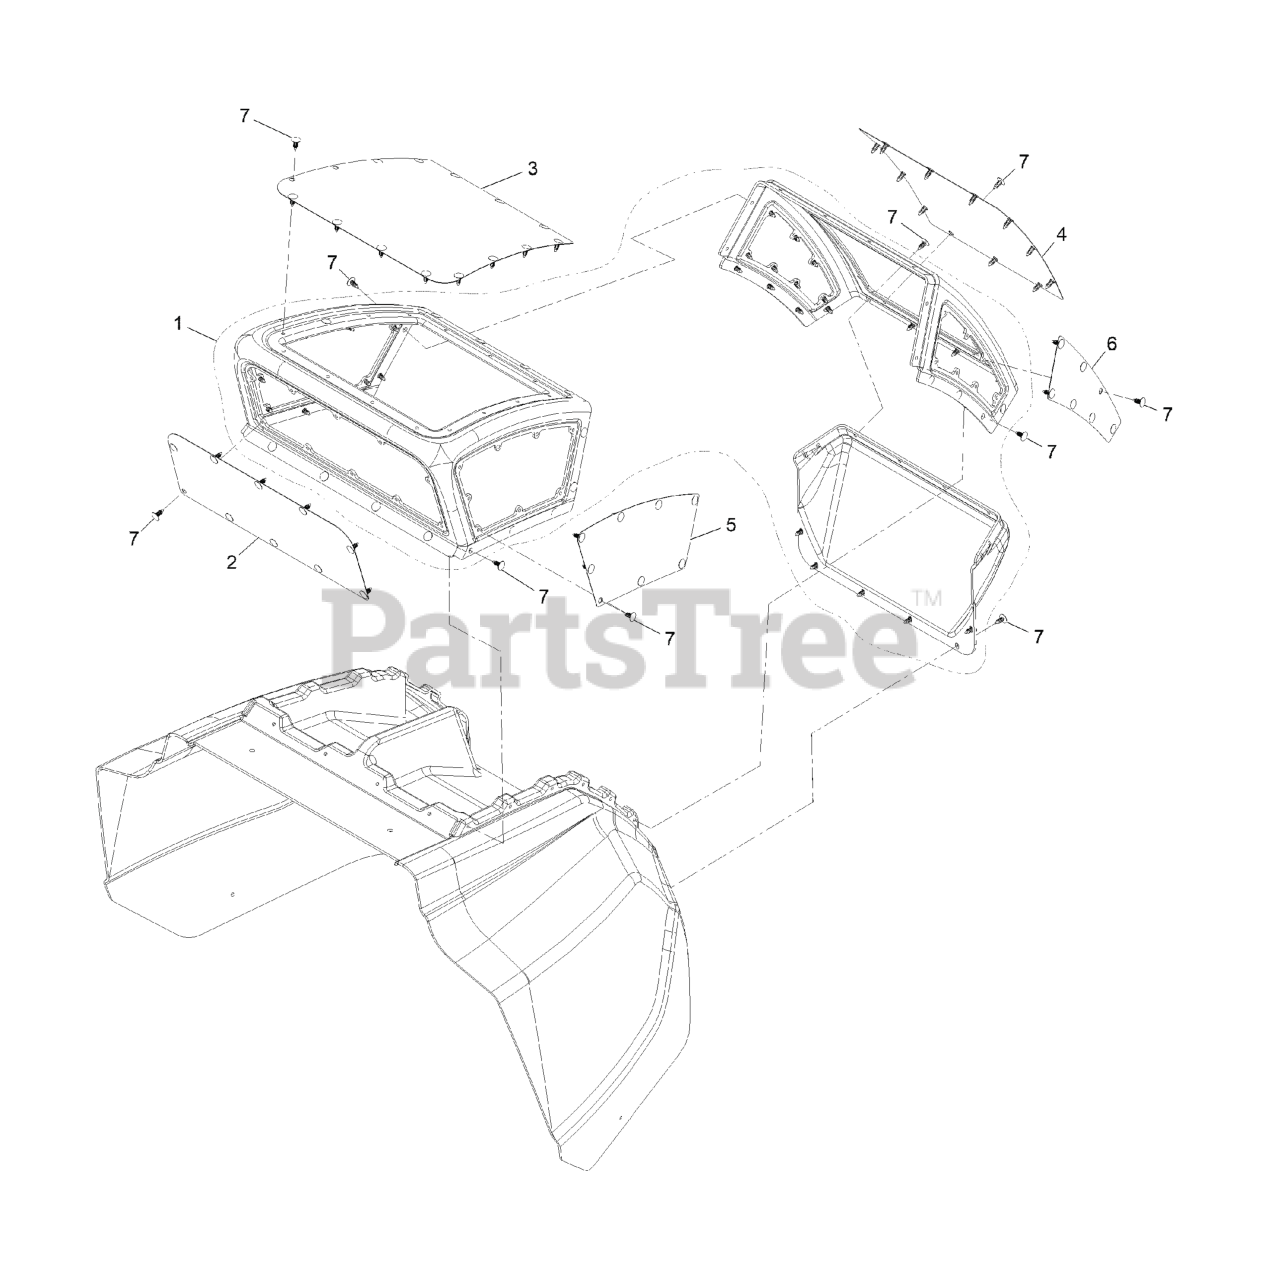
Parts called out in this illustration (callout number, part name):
1	HOOD-INTAKE
2	Screen-Intake [black]
3	Screen-Intake [black]
4	Screen-Intake [black]
5	Screen-Intake [black]
6	Screen-Intake [black]
7	PLUG-PLASTIC
